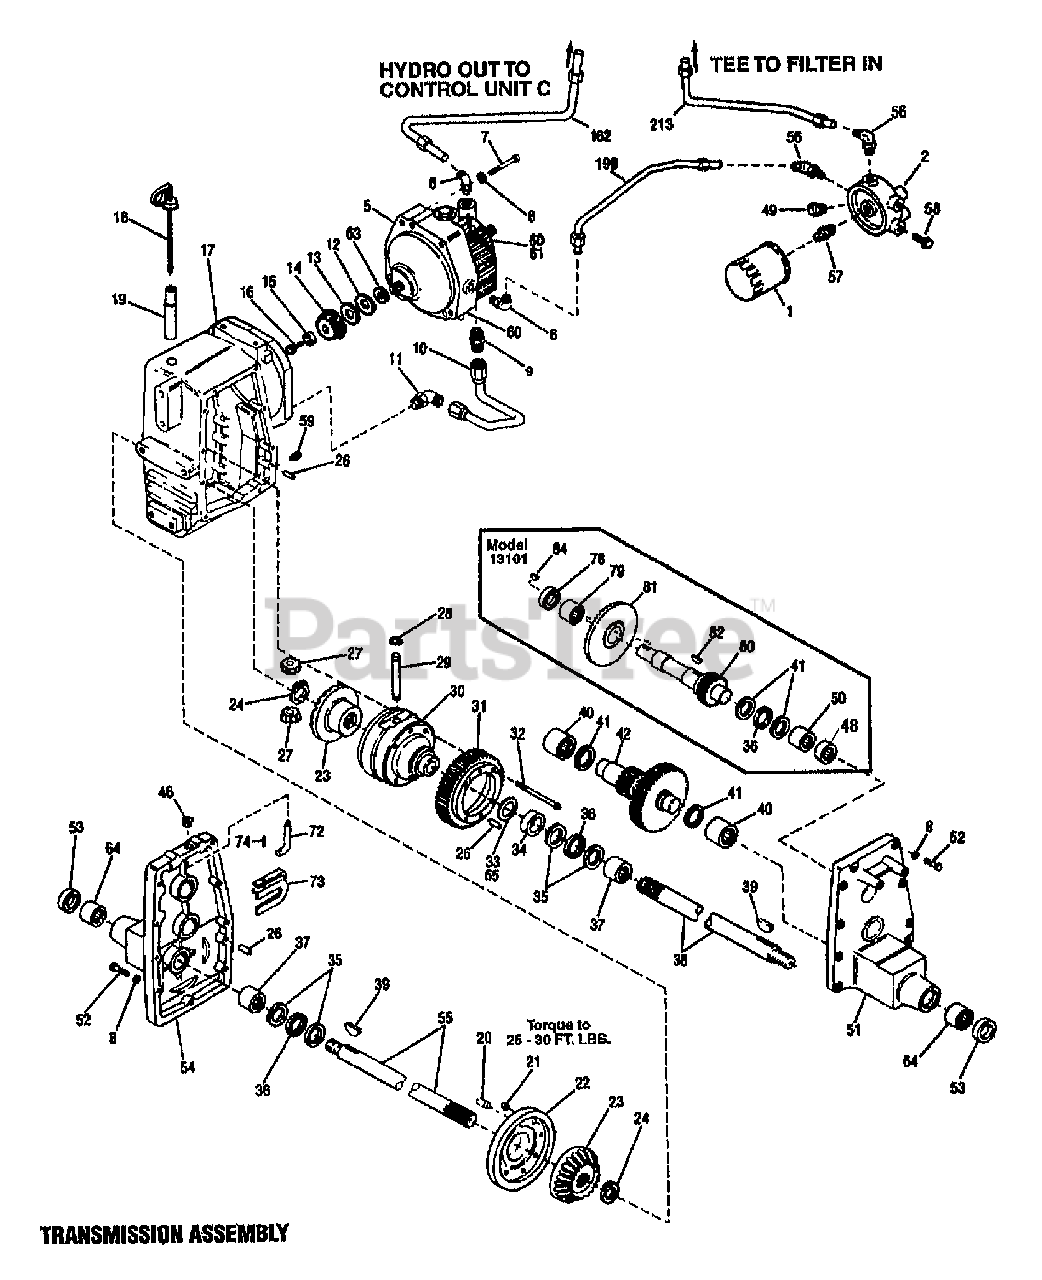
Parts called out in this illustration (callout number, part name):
1	FILTER-OIL
2	FILTER-MANIFOLD
5	PUMP-HYDRO
6	ELBOW
7	SCR-HH 3/8-16X2.75 G5 ZP
8	WASHER-LK .375 @ DEPL
9	CONNECTOR
11	ELBOW
12	WASHER-SHIM
13	WASHER-SHIM
14	PINION-BEVEL
15	SPACER-1.0X.25X.25
16	SCR-HH 1/4-20X.625 G5 ZP
17	HOUSING-TRANSAXLE
18	DIPSTICK
20	PIN-.312X.75
21	NUT-HEX/LK 5/16-18 G5ZP
22	COVER-DIFFERENTIAL
23	GEAR-23T
24	RING-HEAVY EXT HD 1.0 ID
26	PIN-DOWEL .375X1.00 ZP
27	PINION-10T
28	RING-HEAVY EXT .625 ID
29	PINION-SHAFT
30	CARRIER-DIFFERENTIAL
31	GEAR-AXLE 47T
32	SCR-HFLK 5/16-18X4.00 ZP
33	SHIM-1.875X1.013X.015
34	SPACER-1.5X1.01X.45
35	RACE-THRUST
36	BEARING-THRUST
38	AXLE-RH
39	KEY-WOODRUFF .312X1.12
40	BEARING-NEEDLE
41	RACE-THRUST
42	ASSM-GEAR CLUSTER
48	PLUG-EXPANSION
49	SWITCH-TEMPERATURE
50	BEARING-NEEDLE
51	COVER-TRANSAXLE RH
52	SCR-HH 3/8-16X1.5 G5 ZP
53	SEAL-OIL
54	COVER-TRANS LH
55	AXLE-LH
56	ELBOW
57	COUPLING
59	PLUG-PIPE
60	SEAL-OIL
61	SHIELD-GRASS
63	WASHER-1.0X.64X.029
64	BEARING-NEEDLE
78	SEAL-OIL
79	BEARING-NEEDLE
80	ASSM-PINION SHAFT
82	KEY-WOODRUFF .25X1
84	KEY-WOODRUFF .25X.75
162	TUBE-HYDRO PRESSURE
199	ASSM-RETURN TUBE
213	ASSM-TUBE
